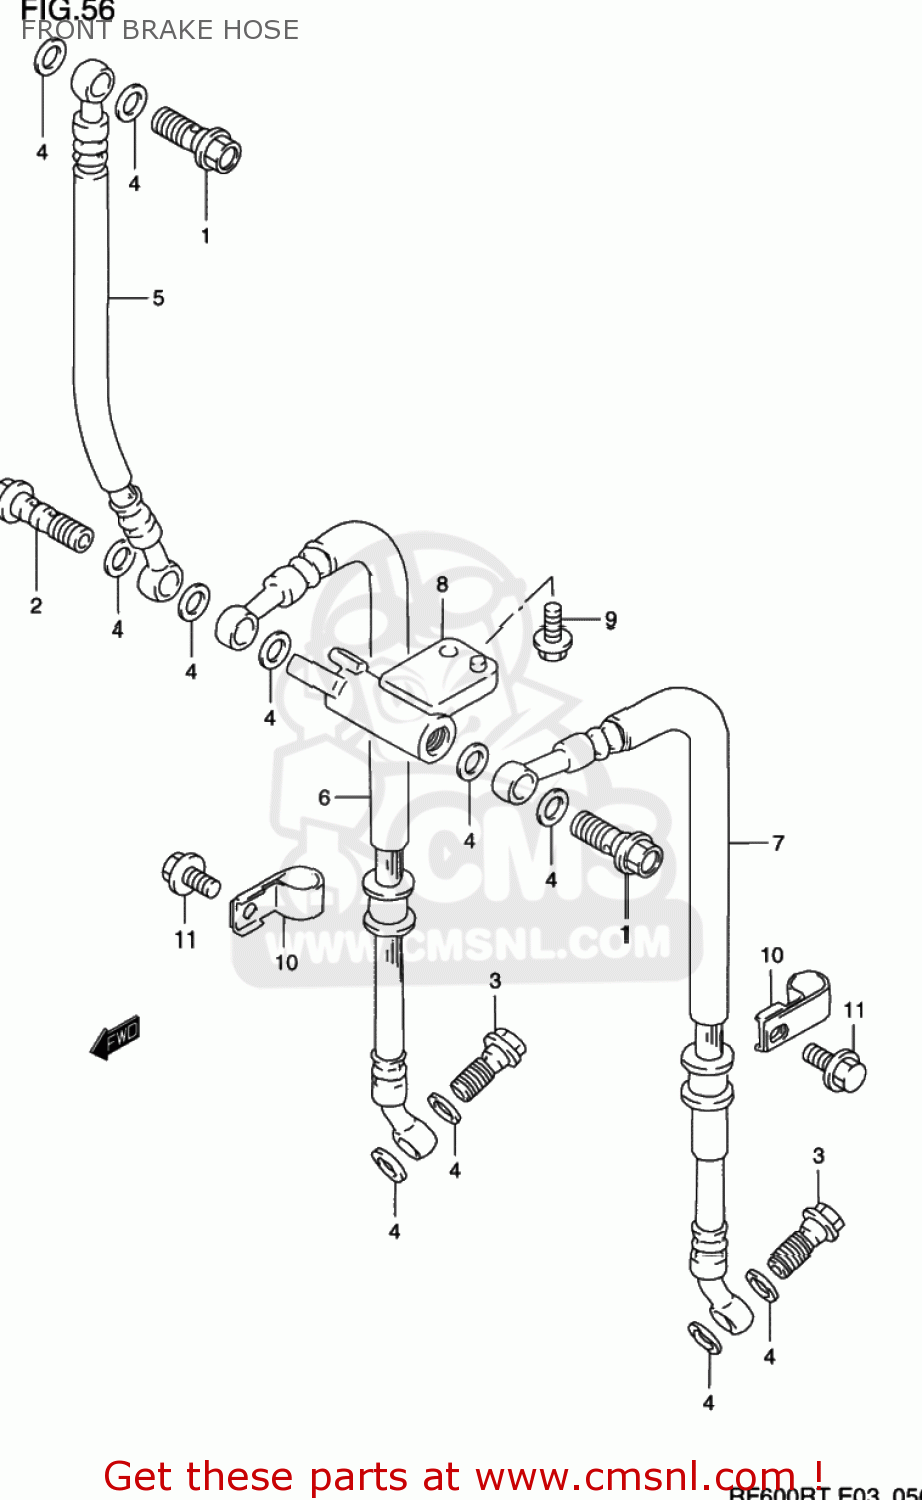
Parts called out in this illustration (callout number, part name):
1	BOLT UNION
2	BOLT UNION
3	BOLT UNION
4	WASHER(10X15X1.5)
5	HOSE,FR BRAKE NO.1
6	HOSE,FR BRAKE NO.2,R
7	HOSE COMP,FRONT BRAKE
8	JOINT,BRAKE HOSE
9	BOLT
10	CLAMP,FR BRAKE HOSE NO.2
11	BOLT
